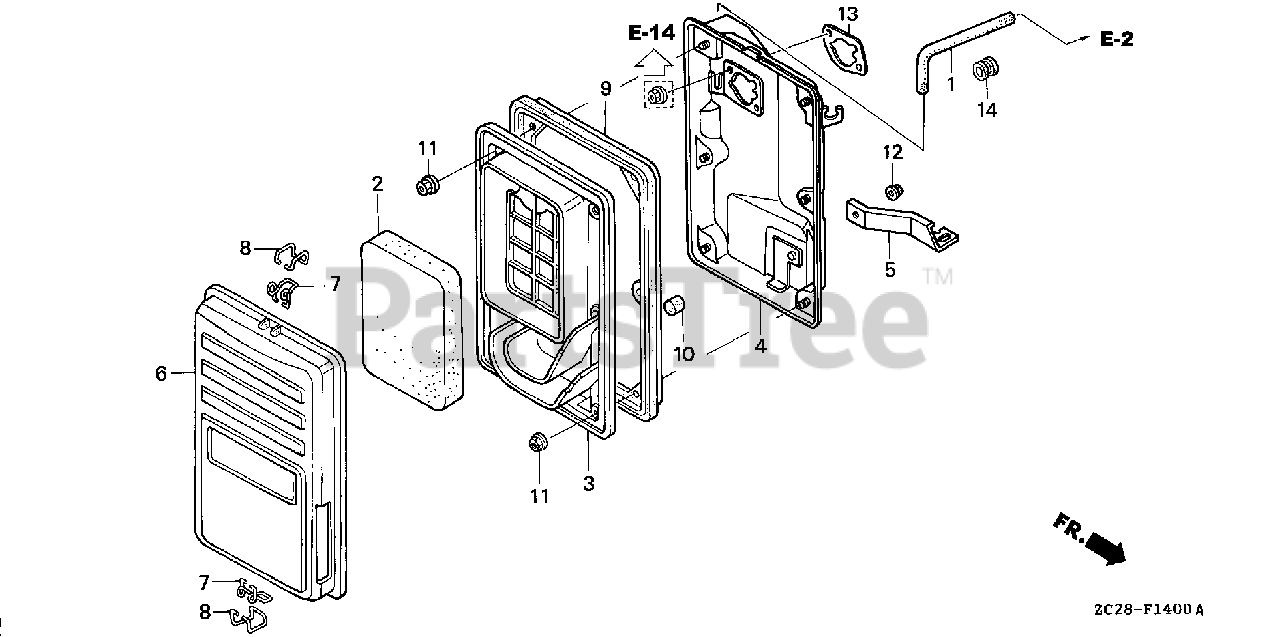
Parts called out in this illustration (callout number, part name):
1	TUBE, BREATHER
2	ELEMENT, AIR CLEANER
3	SEPARATOR, AIR CLEANER
4	HOUSING, AIR CLEANER
5	STAY, AIR CLEANER
6	COVER, AIR CLEANER
7	CLIP A, AIR CLEANER WIRE
8	CLIP B, AIR CLEANER WIRE
9	SEAL, AIR CLEANER
10	FILTER, DRAIN TUBE
11	NUT, FLANGE (5MM)
12	NUT, FLANGE (6MM)
14	GROMMET, FENDER
